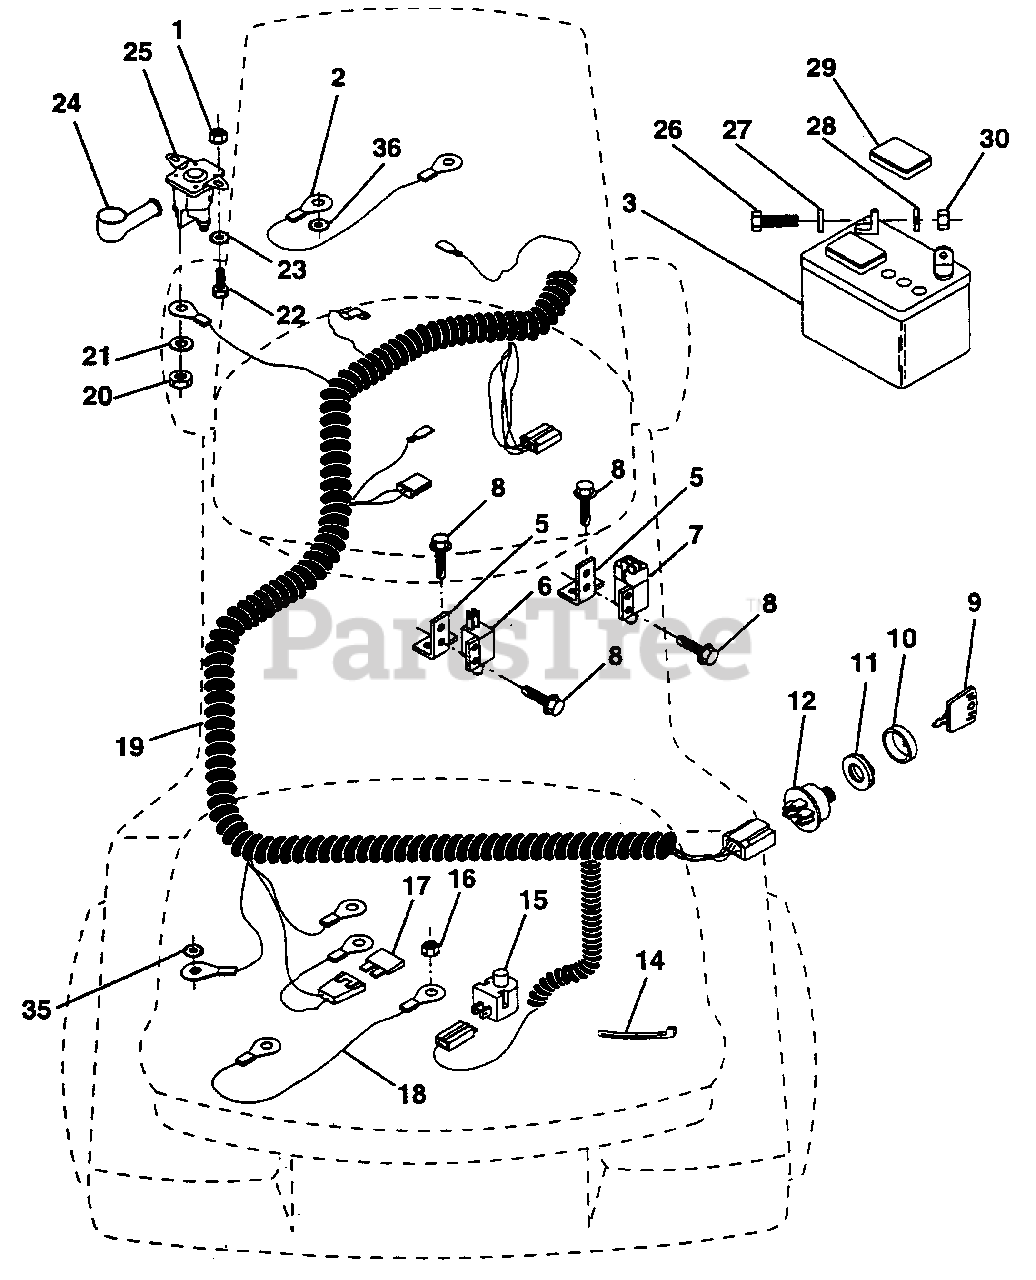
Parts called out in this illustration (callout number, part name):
1	Nut, Hex Keps 1/4-20
2	Assembly, Cable
3	Battery
5	Bracket, Switch
6	Switch, Interlock (2-terminal)
7	Switch, Interlock (4-terminal)
8	Screw, Hex Hd. Tap #10-24 x 1/2
10	Cover, Key Ignition
11	Nut, Ignition
12	Switch, Ignition
14	Tie, Cable
15	Switch, Plunger
16	Nut, Hex, Keps 5/16-18
18	Assembly, Cable
19	Harness, Ignition
20	Nut, Hex Jam 1/4-20
21	Washer, Lock 1/4
22	Bolt, Fin Hex 1/4-20 UNC x 1/2 Gr. 5
23	Washer, Lock Ext. Tooth 1/4
24	Cover, Terminal
25	Solenoid
26	Bolt, Hex Hd. 1/4-20 UNC x 3/4
27	Washer 9/32 x 5/8 x 16
28	Washer, Lock 1/4
30	Nut, Fin Hex 1/4-20 UNC
35	Washer, Lock Ext. Tooth 3/8
36	Washer, Lock Ent. Tooth 5/16
